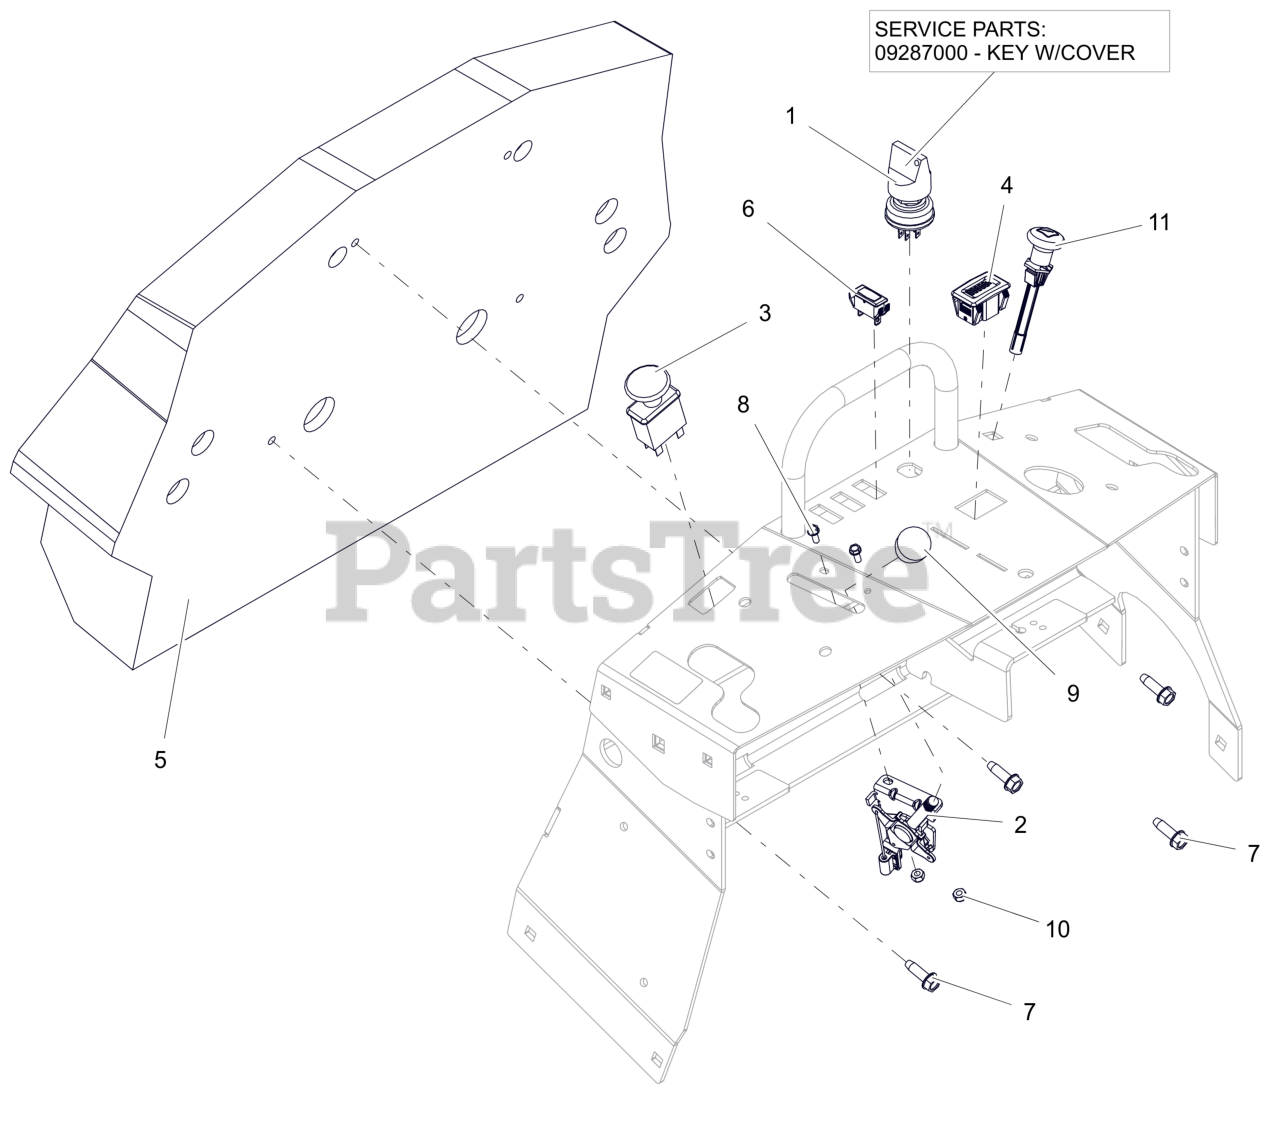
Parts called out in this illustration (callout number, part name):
1	SWITCH, IGNITION
1	KEY, W/ SHIELD
2	CABLE, PROSTANCE - CONTROL 43"
3	SWITCH, CLUTCH
4	HOUR METER
5	PAD, OPERATOR - PROSTANCE
6	LIGHT, INDICATOR (RED)
7	SCR-TAP .312-18X1.00 HWH ZCC
8	BLT, HWH #10-24X.50 ZCC
9	KNOB-CONTROL-BLACK .38-16X.50
10	NUT-LK-NYL #10-24 G2 ZCC
11	CABLE, CHOKE (SNAP IN)
